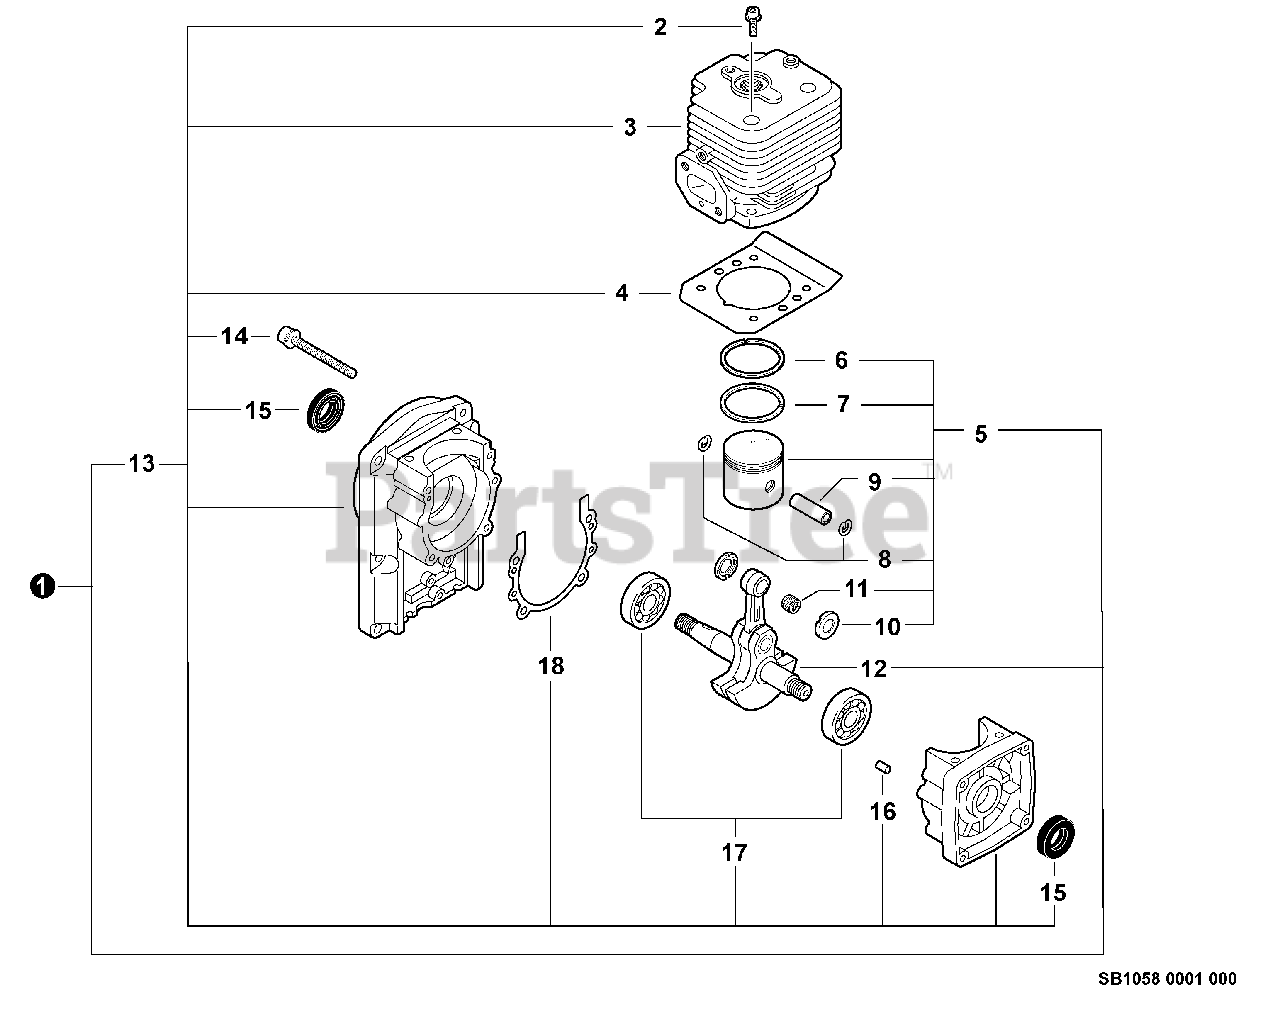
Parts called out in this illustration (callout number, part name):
1	SHORT BLOCK -- SB1058
2	SCREW - 5X22
3	CYLINDER
4	GASKET, CYLINDER
5	PISTON KIT
6	RING, PISTON
7	RING, PISTON
8	RING, RETAINING - 8
9	PIN, PISTON
10	WASHER - 10
11	BEARING, NEEDLE - 10
12	CRANKSHAFT ASSY
13	CRANKCASE KIT
14	SCREW - 5X35
15	SEAL, OIL
16	PIN - LOCATING
17	BEARING, BALL - 6302
18	GASKET, CRANKCASE
